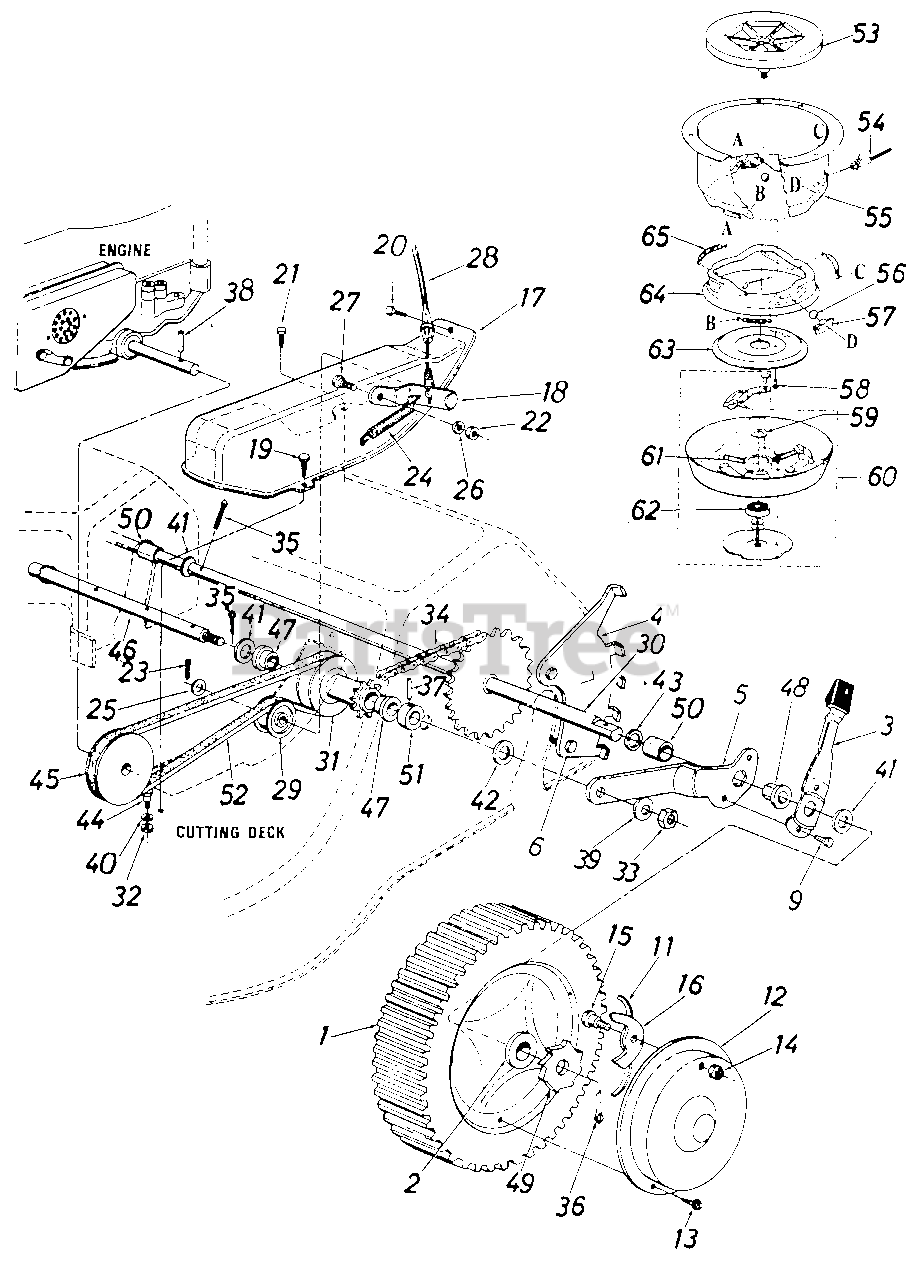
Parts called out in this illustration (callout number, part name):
1	Wheel Ass'y. Comp. 8.0 x 1 .75
2	Flange Brg.-1/2" I.D.
3	Spring Lever wlKnob
4	Index Plate Ass'y.-L.H.
5	Pivot Brkt.-L.H.
6	Hex Wash. Hd. Tap Scr. 1/4 x.62"
9	Hex B-Tap Scr. 1/4 x .38"
11	Nylon Spring
12	Hub Cap
13	Pan Hd. Tap Scr. #12 x .50"
14	Hex Ins. L-Nut 1/4-20 Thd.
15	Shld. Bolt .342" Dia. x .268
16	Pawl
17	Belt Cover
18	Idler Bracket Ass'y.
19	Hex Wash. Hd. Self-Tap Scr. 1/4-20 x .50" Lg.
20	Hex Drilling Scr. #10 x .50"
21	Hex TT-Tap Scr. 1/4-20 x .75"
22	Hex Nut 1/4-20 Thd.
23	Cotter Pin 118" Dia. x 1.00"
24	Extension Spring .33" O.D. x 1.12" Lg.
25	Fl-Wash. .531" I.D. x .930" O.D.
26	L-Wash. 1/4" I.D.
27	Shld. Bolt .375" Dia. x .181
28	Clutch Cable-50"
29	Flat Idler-Plastic
30	Rear Shaft Ass'y.
31	Pulley wl9 Tooth Sprocket Ass'y.
32	Hex Nut 5/16-18 Thd.
33	Hex Jam Nut 3/8-16 Thd.
34	#48 Chain 1/2" Pitch x 31 Li nks
35	Cotter Pin 3132" Dia. x 1.00"
36	Cotter Pin 1/8" Dia. x 1.00"
37	Spring Pin Spir. 3/16" Dia. x 1.00" Lg.
38	Spring Pin Spir. 3/16" Dia. x 1.50" Lg.
39	Bell-Wash. 400n I.D. x .88" O.D.
40	L-Wash. 5/16" I.D.
41	Fl-Wash. .531" I.D. x .930" O.D.
42	Bell-Wash. .400" I.D. x 1.13" O.D.
43	Fl-Wash. .510" I.D. x 1.0" O.D.
44	Shld. Bolt .437" Dia. x 850"
45	Engine Pulley
46	Pulley Shaft-10.0" Lg.
47	Flange Brg. .506" I.D. Plastic
48	Hex Flange Brg. .506" I.D. Plastic
49	Ratchet
50	Spacer.765" I.D. x .89" O.D. x.960" Lg.
51	Spacer. 505" I.D. x .88" O.D. x.44" Lg.
52	"V"-Belt 1/2" x 33" Lg.
53	Fan Adapter
54	Clutch Cable-46"
55	Clutch Housing
56	Steel Ball .50" Dia.
57	Ball Block
58	Hex TT-Tap L-Scr. 1/4-20 x .75" Lg.
59	Fl-Wash. .69" I.D. x 1.06"
60	Clutch Blade Housing Ass'y.
61	Compression Spring .35" O.D. x 2.00" Lg.
62	Ball Brg. .669" I.D. x 1.574" O.D. x .47
63	Clutching Cone
64	Brake Cup Cone
65	Extension Spring .35" O.D. x 1.75" Lg.
